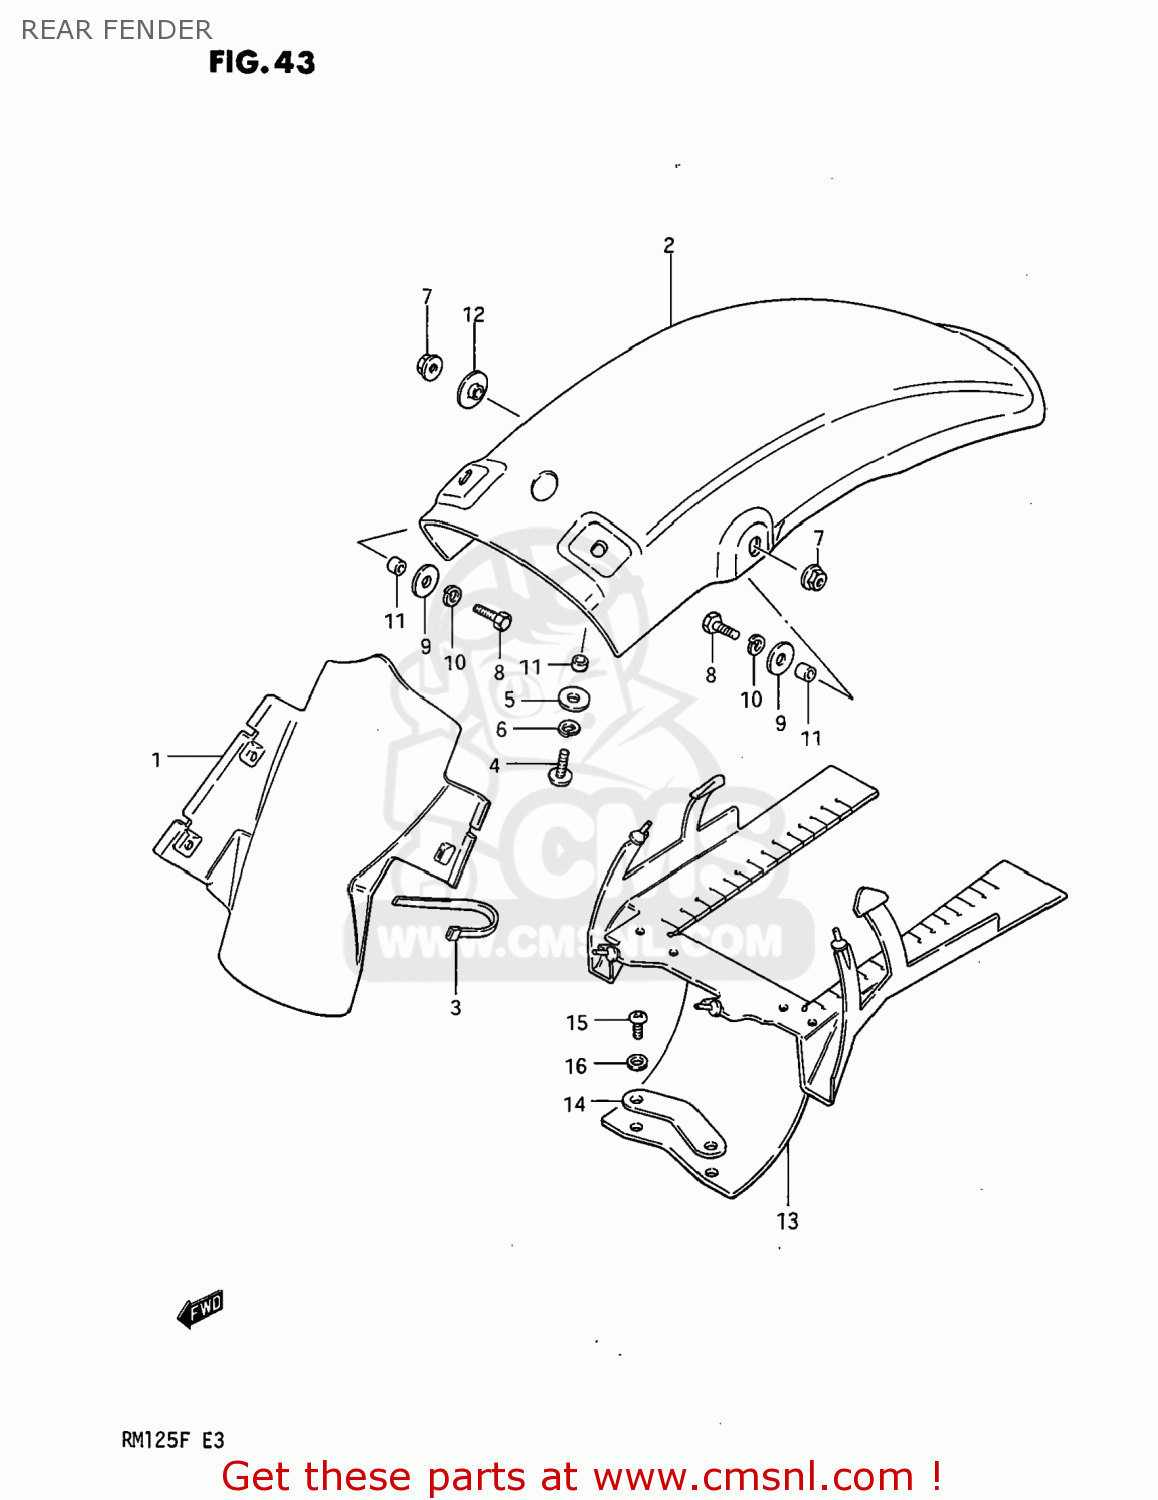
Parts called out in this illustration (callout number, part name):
1	BODY,REAR FENDER,FRONT
2	FENDER,REAR
3	CLAMP
4	SCREW
5	WASHER
6	LOCK WASHER
7	NUT
8	BOLT
9	WASHER (6.5X20X1.2)
10	LOCK WASHER
11	SPACER
12	WASHER
13	MUD GUARD,REAR FENDER
14	PLATE,MUD GUARD
15	SCREW
16	WASHER
